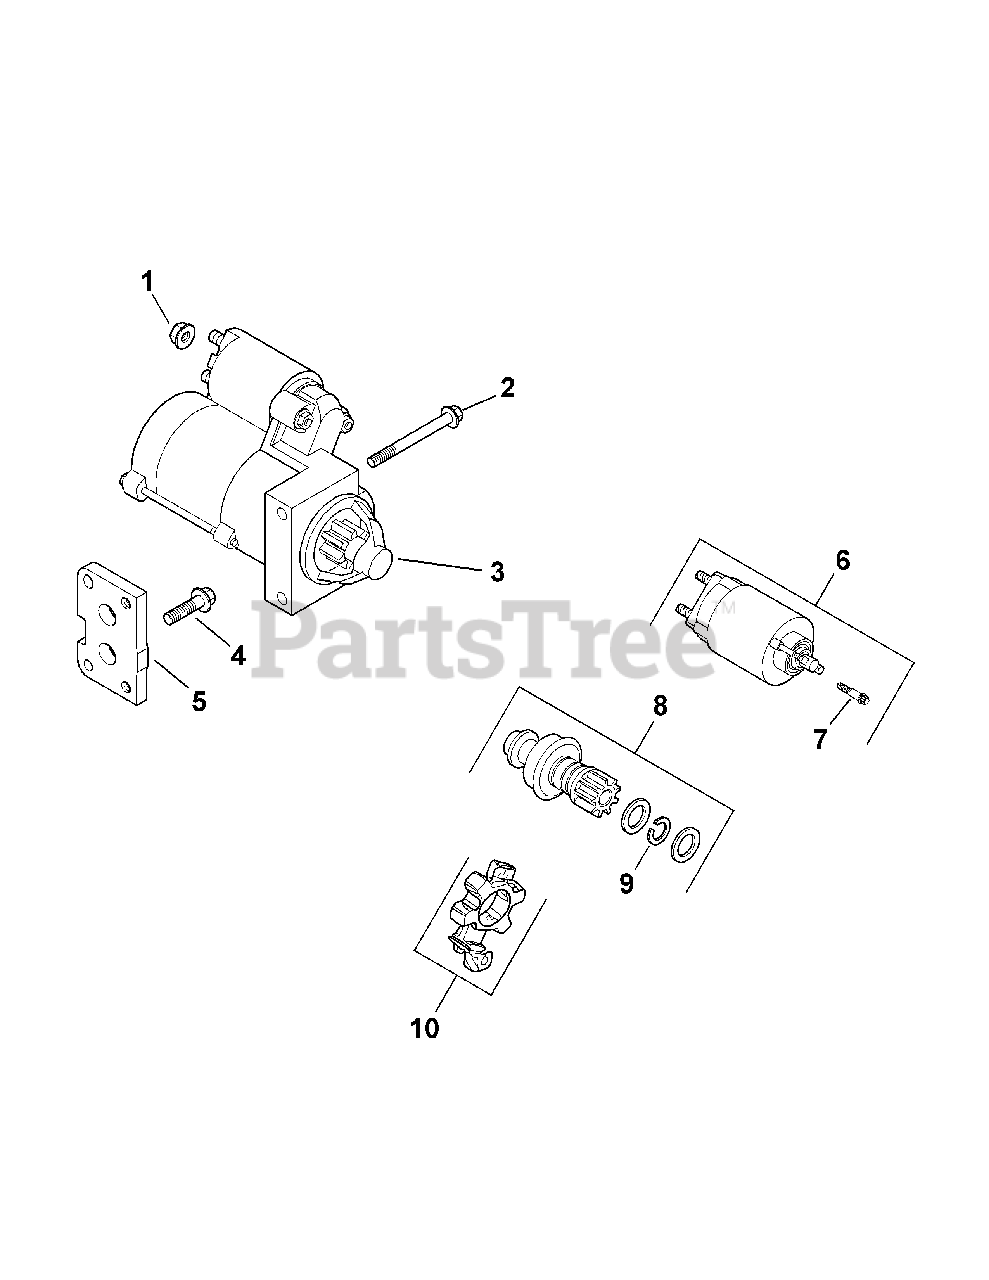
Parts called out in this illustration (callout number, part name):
1	NUT, FLG M8X1.25
2	SCREW, FLG M8X1.25X80
3	STARTER ASSY, SOLENOID SHIFT
4	SCREW, FLG M8X1.25X30
5	PLATE, STARTER
6	KIT, SOLENOID
7	SCREW, EXTERNAL TORX HEAD
8	KIT, STARTER PINION
10	BRUSH, HOLDER
